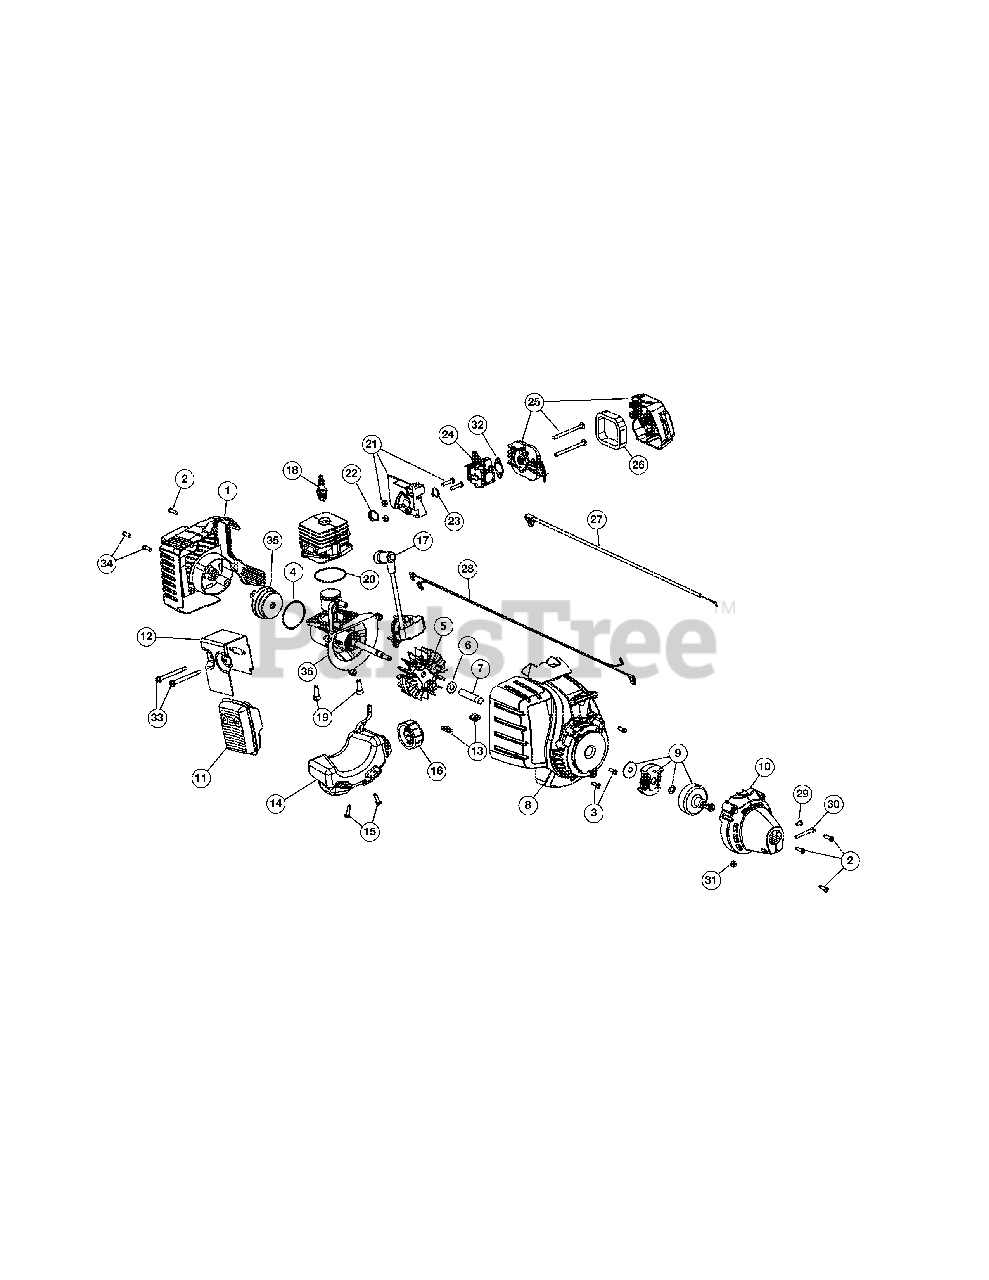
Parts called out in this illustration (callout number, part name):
1	Rear Cover Assembly (Incl. Ref No. 2 & 34)
2	Cover Screw
3	Housing Screw
5	Flywheel Assembly
8	Starter Housing (Incl. Ref No. 3 & 13)
9	Clutch Assembly
10	Clutch Cover (Incl. Ref No. 2)
11	Muffler Assembly (Incl. Ref No. 12 & 33)
12	Muffler Gasket
13	U-shaped Nut
14	Fuel Tank Assembly (Incl. Ref No. 15 & 16)
17	Module Assembly
18	Spark Plug
19	Crankcase Bolt
20	Crankcase O-Ring
21	Insulator Assembly (Incl. Ref No. 22 & 23)
22	Insulator O-Ring
23	Carburetor O-Ring
24	Carburetor
25	Aircleaner Cover Assembly (Incl. Ref No. 26)
26	Aircleaner Filter
27	Throttle Cable
28	Lead Wires
29	Anti-rotation Screw
30	Clamp Screw
31	Clamp Nut
32	Air Cleaner Gasket
33	Muffler Screw
34	Rear Housing Screw
35	Electric Starter Cover Assembly
36	Short Block Assembly (Incl. Ref No. 4-7 & 17-20)
